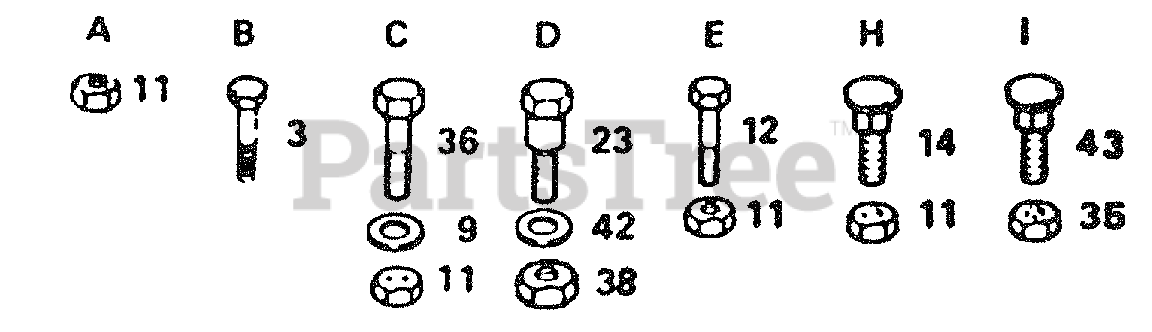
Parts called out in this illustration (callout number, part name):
3	Screw-Tap. Hex Hd. 10-24 x 1/2
9	Washer 13/32 x 13/16 x 12 Ga.
11	Nut-Crownlock 3/8-16
12	Bolt, Carr. 3/8-16 x 1
14	Bolt, Carr. 3/8-16 x 3/4
23	Bolt-Shoulder 3/8-16
35	Nut, Lock 5/16-18
36	Bolt-Hex 3/8-16 x 1
38	Nut, Centerlock Flange 3/8-16
42	Spring Washer
43	Bolt, Carr. 5/16-18 x 3/4
